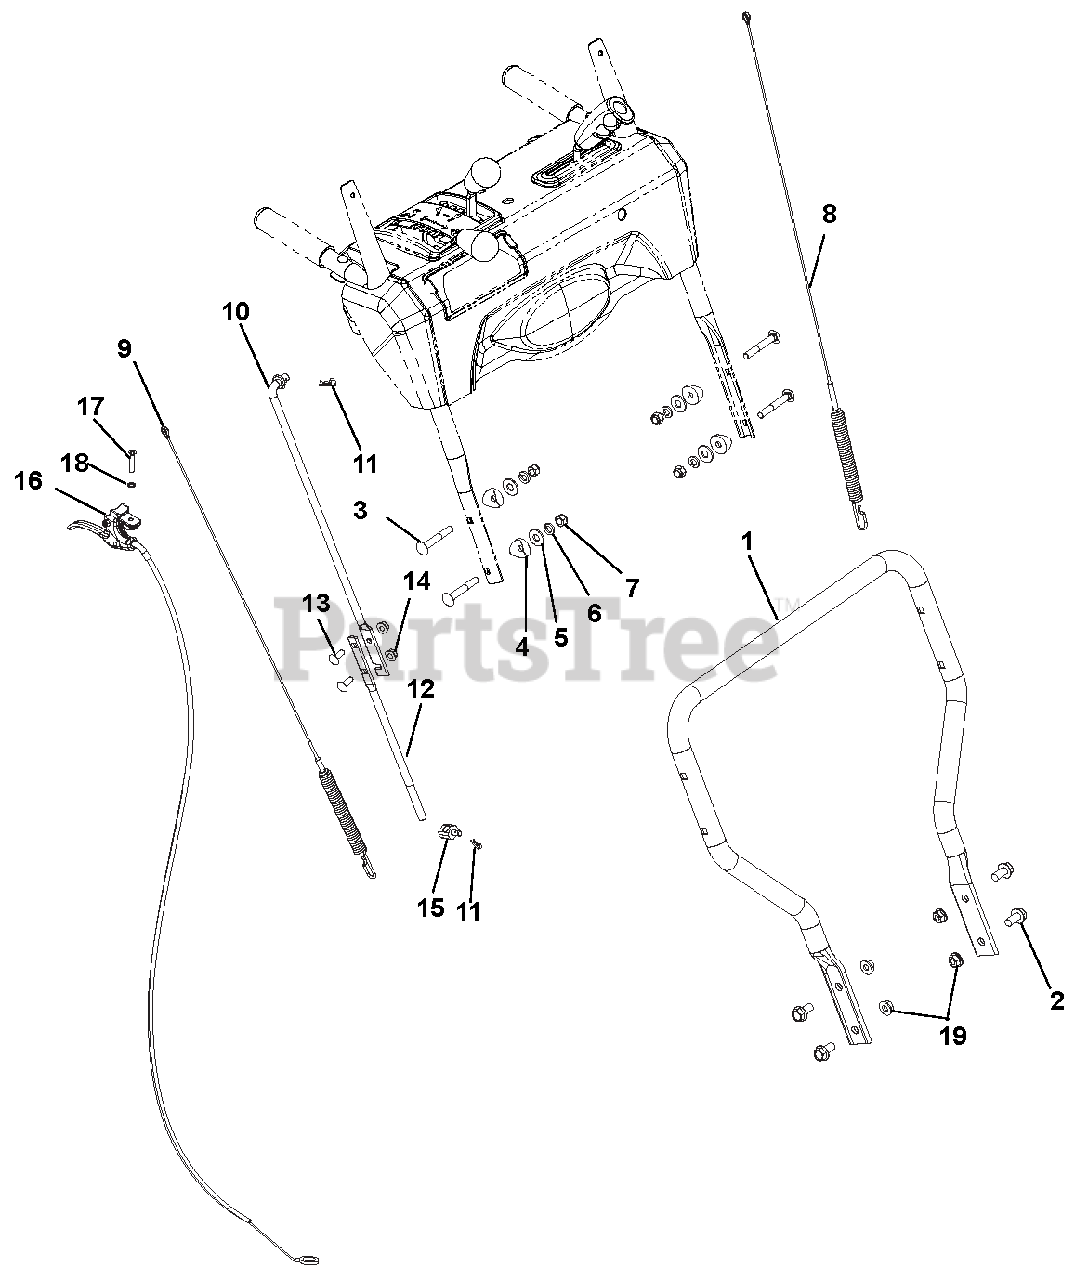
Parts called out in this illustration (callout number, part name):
1	HANDLEBAR, LOWER
2	BLT-SERHFWH .38-16X.75 YWZC
3	@BLT-RDHDSQNK .31-18X2.25 G5YZ
4	SPACER, HANDLEBAR
5	@WSHR-FL-STL.38X.875X.083 YWZC
6	WSHR-LK .312X.097 HVY YWZC
7	@NUT-LK-NYL .312-18 YWZC
8	CABLE, UPPER TRACTION
9	CABLE, AUGER (DELUXE & PRO)
10	ROD, SHIFT - UPPER
11	PIN-HAIR INT .08X.18X1.18 YWZC
12	ROD, SHIFT - LOWER
13	@BLT-RDHDSQNK .25-20X.75 G5YZ
14	@NUT-LK-TOP-FLG .25-20 YWZC
15	PIVOT,SHIFT ROD .375-16(TRUNN)
16	CABLE, CONTROL SWING-MCD
17	SCR-MCH .25-20X1.50 OVAL HD
18	WSHR-LK-INT .250 TH TYA
19	@NUT-LK-TOP-FLG .38-16 YWZC
